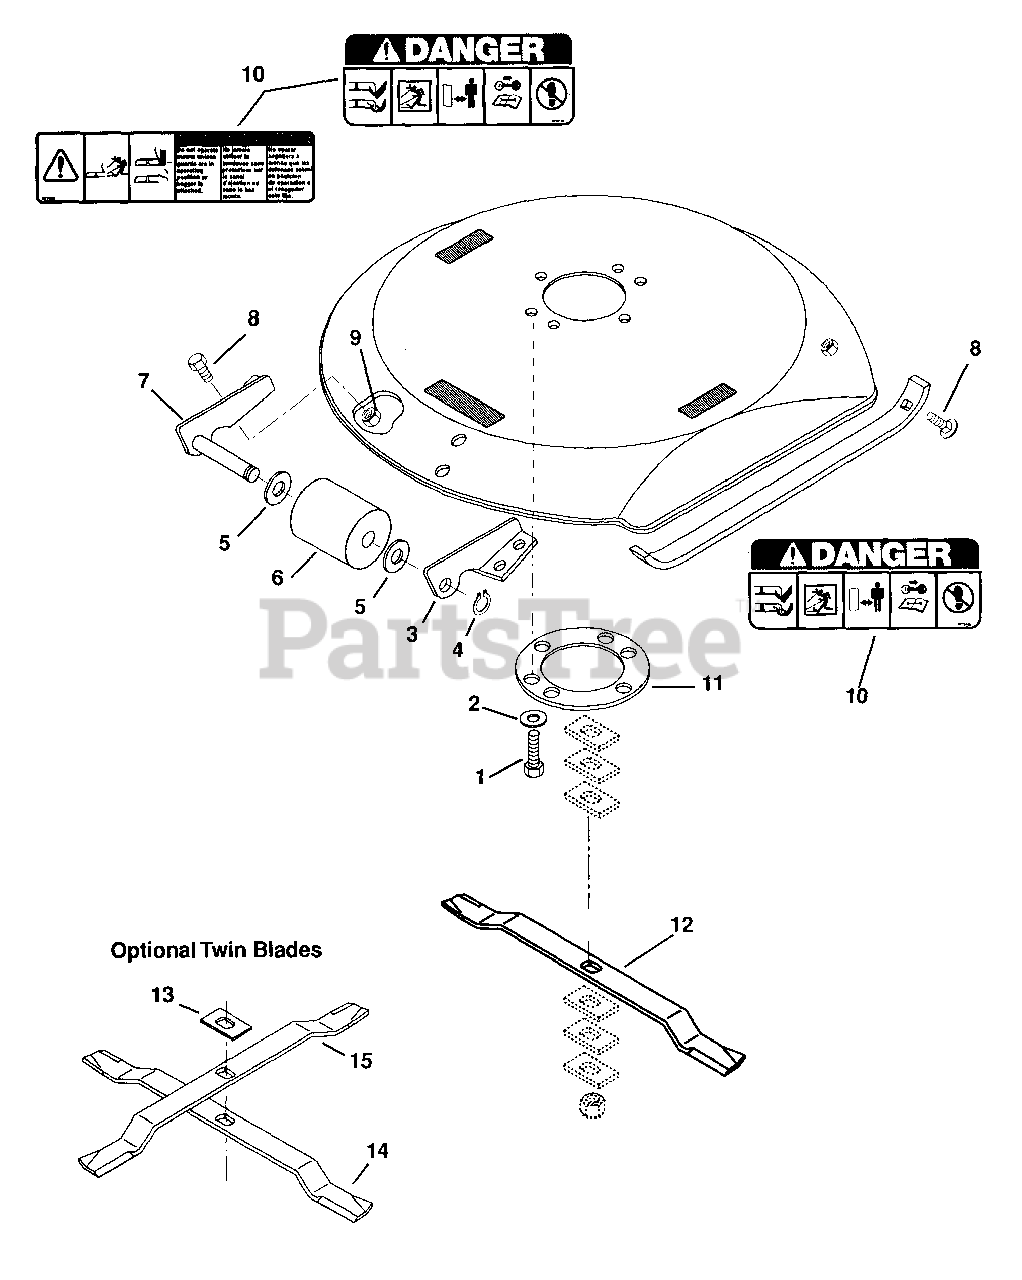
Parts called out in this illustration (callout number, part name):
1	Bolt-Hex .50-13 x 1.75 Grade 5
2	Washer-Flat-Steel .563 x 1.38 x .109
3	Bracket-Wheel LH
4	Ring-Retaining-External .625 x .042
5	Washer-Flat-Stainless-Steel .656 x 1.25 x .1
6	Roller-Gage
7	Weldment-Bracket
8	Bolt-Hex .31-18 x .75 Grade 5
9	Nut-Locking-Nylon .31-18
10	Decal Set Decks
11	Support Deck
12	Rotary Mower Blade .375
13	Spacer-Cutting Height-Thin 1/8
14	Blade-30" Mower-Thin
15	Blade-30" Mower-Thin Cross Slot
